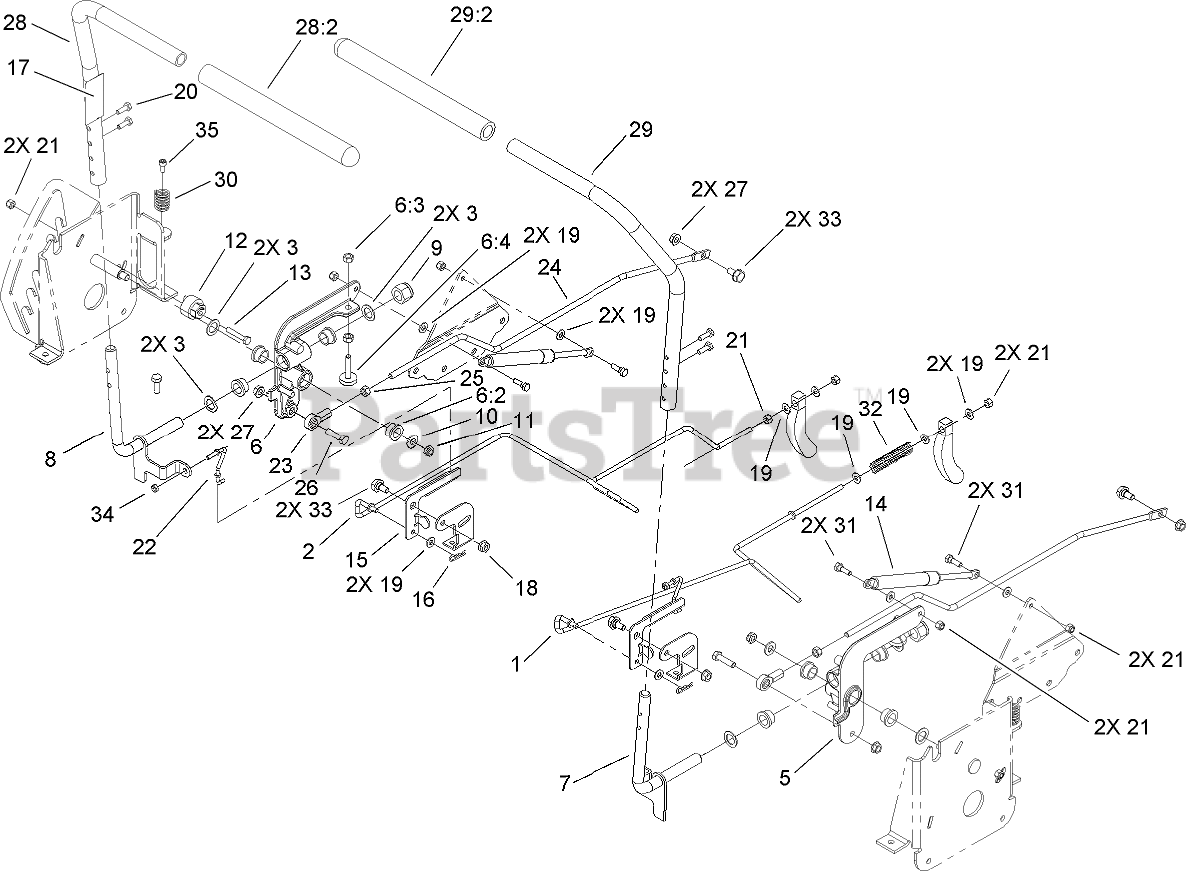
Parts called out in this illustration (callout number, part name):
1	ROD-BRAKE, LH
2	ROD-BRAKE, RH
3	WASHER-THRUST
5	LH ACTIVATOR ARM ASM
6	RH ACTIVATOR ARM ASM
6:2	BUSHING
6:3	NUT-HEX
6:4	STOP-ADJUSTMENT
7	LH PIVOT SHAFT ASM
8	RH PIVOT SHAFT ASM
9	NUT-LOCK, NI
10	WASHER-FLAT
11	NUT-LOCK, NI
12	ECCENTRIC
13	SCREW-HH
14	Damper-Control, Motion
15	BELLCRANK
16	PIN-COTTER
18	NUT-HF
19	WASHER-FLAT
20	SCREW-HH
21	NUT-LOCK, NI
22	LINK-BRAKE
23	BALLJOINT-RH
24	ROD-HYDRO
25	NUT-HEX
26	SCREW-HH
27	NUT-HF
28	RH CONTROL HANDLE ASM
28:2	GRIP-CONTROL, MOTION
29	LH CONTROL HANDLE ASM
29:2	GRIP-CONTROL, MOTION
30	SPRING-COMPRESSION
31	BOLT-SHOULDER
32	SPRING-COMPRESSION
33	BOLT-SHOULDER
34	NUT-LOCK, NI
35	SCREW-HSH
